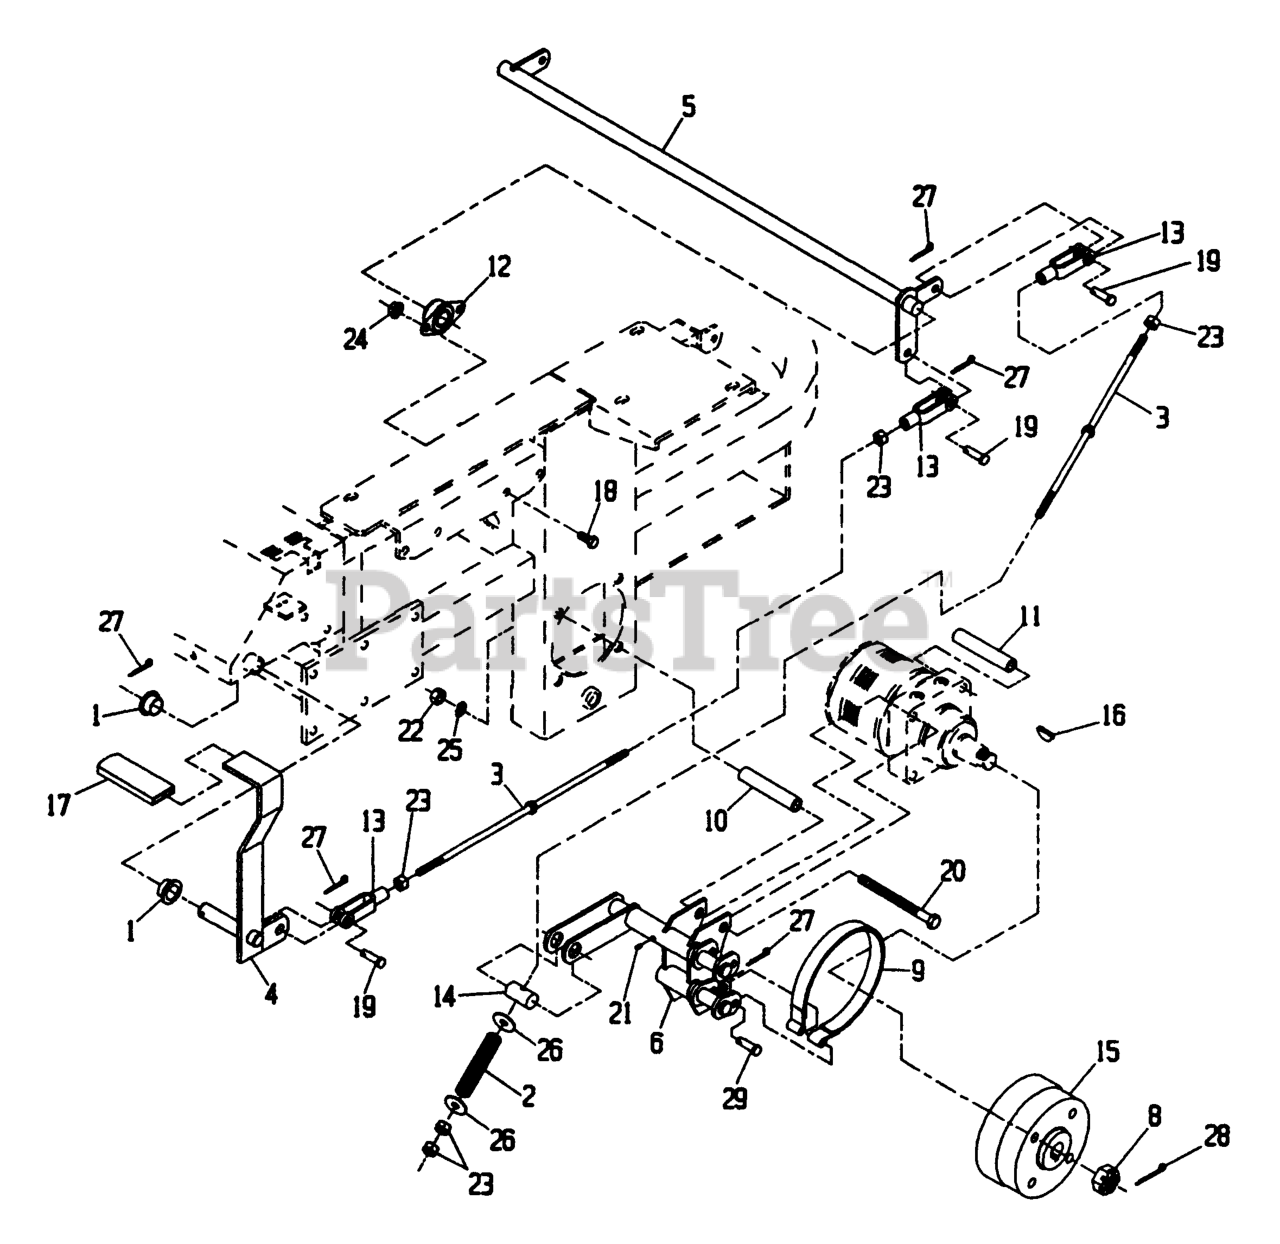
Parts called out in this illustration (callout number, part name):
1	BEARING-CONTROL
2	SPRING-BRAKE
3	ROD-BRAKE
5	SHAFT-BRAKE
10	SPACER-WHEEL, SHORT
12	BEARING-FLANGE, SIDE
13	YOKE-LINKAGE, BRAKE
14	PIN-TRUNION
17	GRIP-LEVER
19	PIN-CLEVIS
28	PIN-COTTER
29	PIN,CLEVIS 3/8X2
